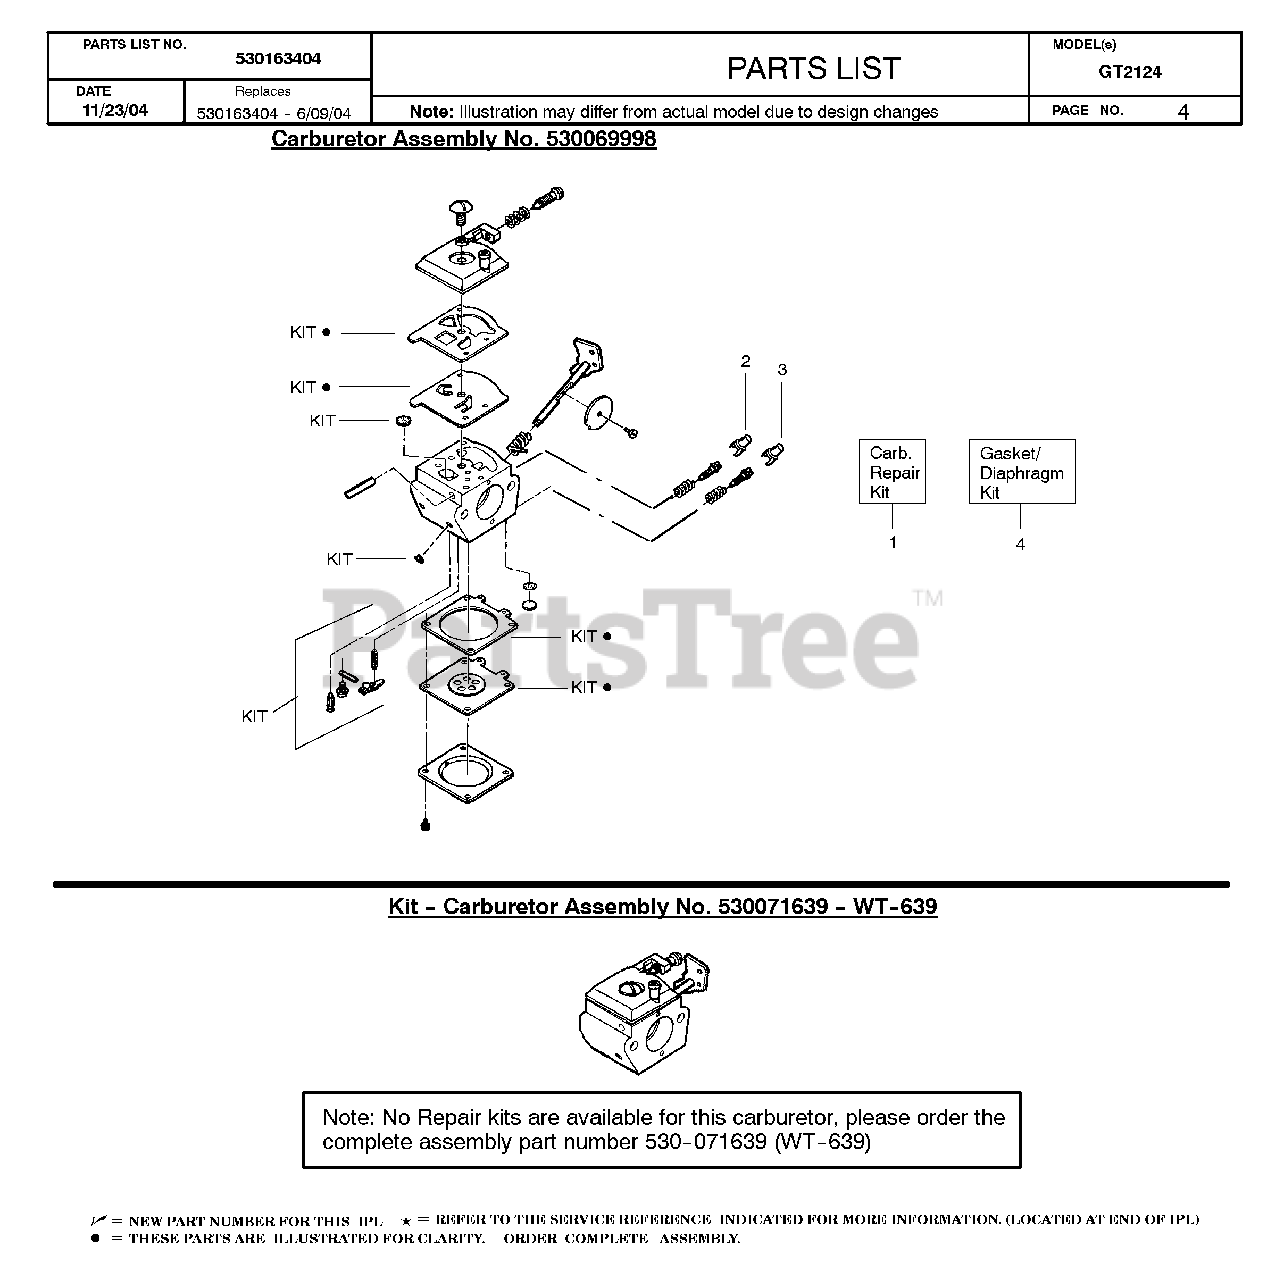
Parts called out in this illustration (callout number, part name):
1	CARB REPAIR KIT
2	LIMITER CAP-HIGH
3	LIMITER CAP-LOW
4	GASKET/DIAPHRAGM KIT
